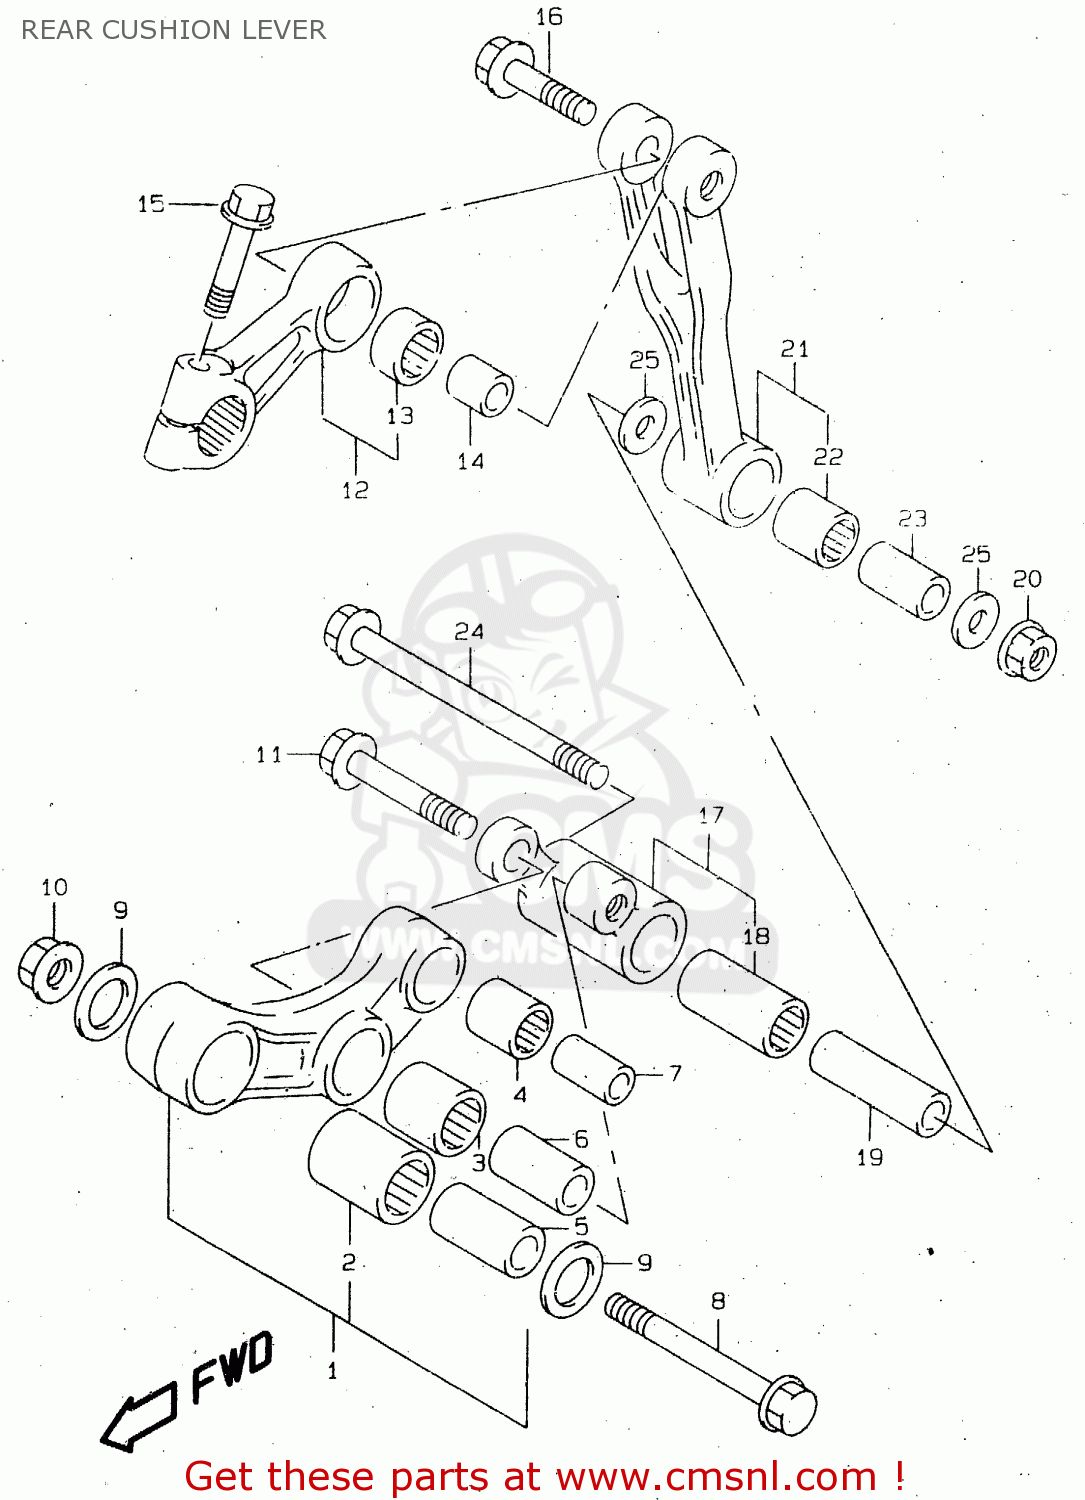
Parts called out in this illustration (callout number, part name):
1	LEVER SET,RR CUSHION
2	BEARING(20X27X32)
3	BEARING(20X27X32)
4	BEARING(17X24X26)
5	SPACER,RR CUSHION LEVER FR
6	SPACER,RR CUSHION LEVER FR
7	SPACER,RR CUSHION LEVER
8	BOLT,RR CUSHION LEVER FR
9	SHIM(20X30X0.5)
10	NUT 12MM
11	BOLT,CUSHION LEVER FR
12	ARM SET,REAR CUSHION
13	BEARING(17X25X16.7)
14	SPACER,RR CUSH ARM
15	BOLT(8X31)
16	BOLT(10X40)
17	ROD SET,RR CUSHION,R
18	BEARING(20X27X23.5)
19	SPACER,RR CUSHION ROD,R
20	NUT 12MM
21	ROD SET,RR CUSHION,L
22	BEARING(20X27X26)
23	SPACER,RR CUSHION LEVER FR
24	BOLT,CUSHION ROD
25	SHIM(20X28X1.5)
